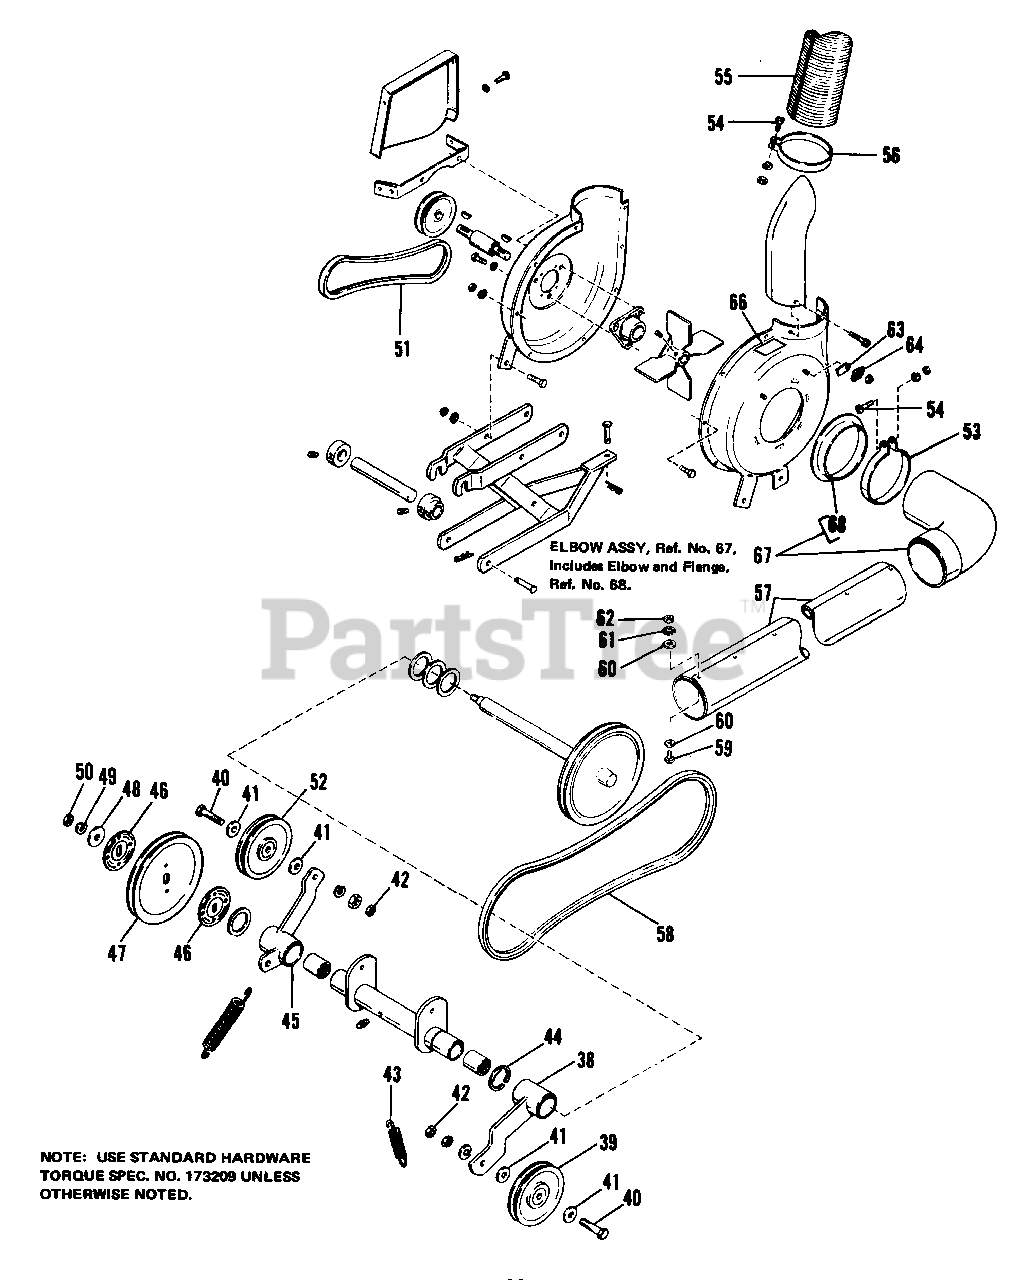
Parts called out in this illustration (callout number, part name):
38	ARM ASSY, Tension
39	PULLEY, Idler
40	CAPSCREW, Hex Hd., 3/8-16 x 2
41	WASHER, Plain, 3/8
42	NUT, Hex, Full Lock, 3/8-16
44	RING, Retaining, 7/16
45	ARM ASSY, Idler
46	WASHER, Special
48	WASHER, Plain, 7/16
49	LOCKWASHER, Spring, 7/16
50	NUT, Hex, 7/16-14
51	BELT, V, Fan Drive
52	PULLEY, Idler
53	CLAMP, Hose
54	SCREW, Rd. Hd., 1/4-20 x 3
55	HOSE, Exhaust
56	CLAMP, Hose
57	TUBE, Intake
58	BELT, V, Vac. Coll. Drive
59	SCREW, Philips Truss Hd.
60	WASHER, Plain, 3/16
61	LOCKWASHER, No. 10
62	NUT, Hex, No. 10-32
64	NUT, Wing
65	NUT, Hex, Full Lock, Jam, 5/16-18 x 3/16
66	DECAL, Caution
68	FLANGE, Hose
